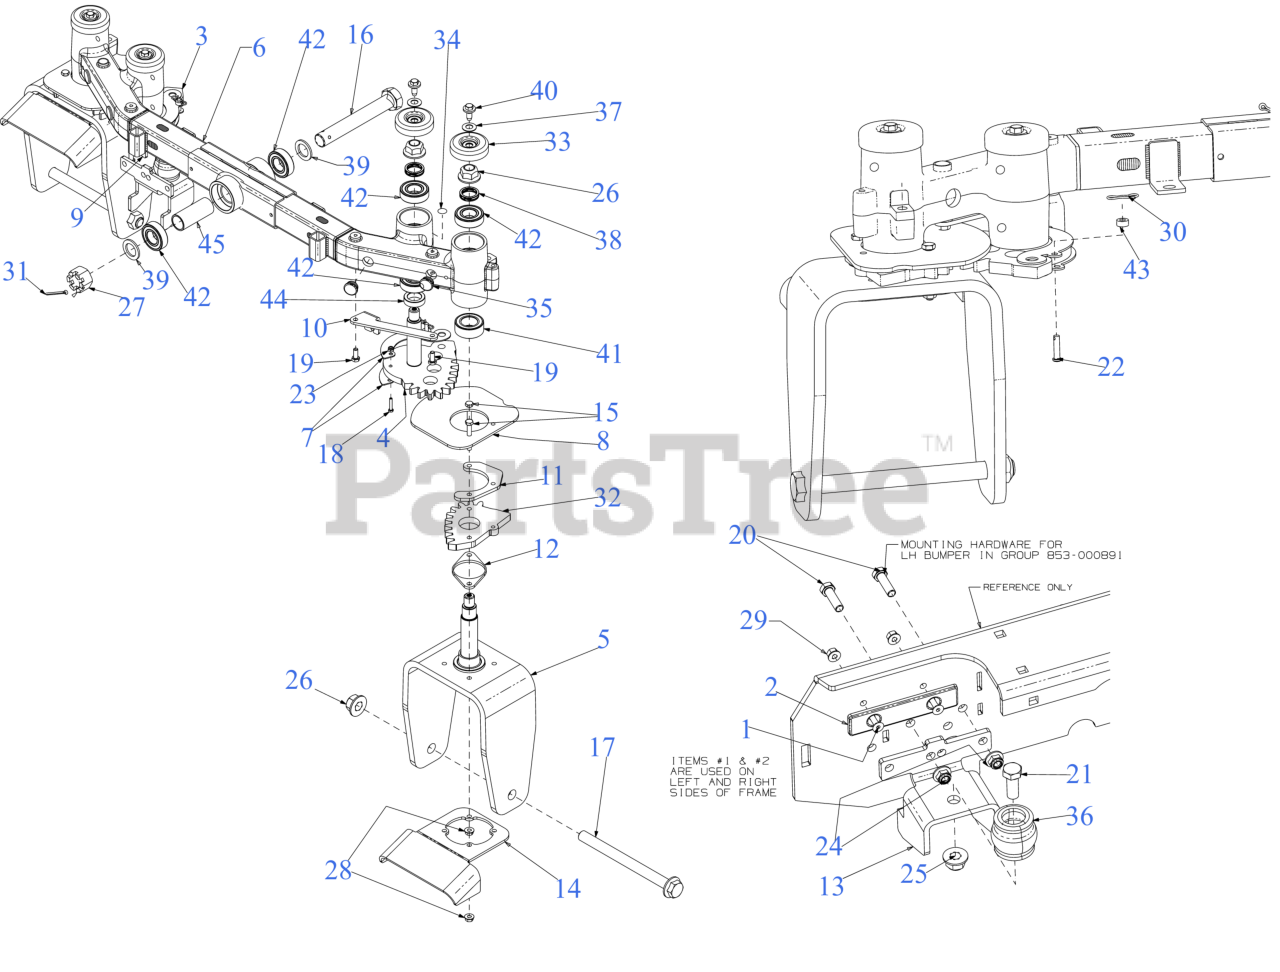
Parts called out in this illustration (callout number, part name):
1	SCREW-FLAT HEAD CA
2	PLATE-LIFT WEAR
3	LEFT HAND STEERING GEAR ASSEMBLY
4	RIGHT HAND STEERING GEAR ASSEMBLY
5	YOKE ASSEMBLY
6	AXLE ASSEMBLY
7	CABLE BEAR MOUNTING BRACKET
12	LOWER GEAR SPACER PLATE
13	BUMPER MOUNTING BRACKET
15	HEX SCREW 5/16-18 x 2.25 GR5
16	HEX HEAD SCREW (1-14 x 7 GR5)
17	SCREW 3/4-16 x 9.00 GR5
18	SCREW #10-24 x 1.00 GR5.1
19	SCREW 5/16-18 x .750
20	SCREW 3/8-16 x 1.25 GR5
21	SCREW 1/2-13 x 1.25 GR5
22	CLEVIS PIN .25 x 1.00
26	FLANGE LOCK NUT 3/4-16 TOP LOCK
27	CASTLE NUT 1.0-14 GR5
28	HEX FLANGE NUT
29	LOCK NUT 1/4
30	BOW TIE COTTER PIN 1/4-5/16
31	SPLIT COTTER PIN 5/32 X 2.00
32	STEERING GEAR YOKE
33	AXLE CAP 2.5"
34	RATCHET CLIP
36	AXIAL BUMPER
37	BELL WASHER
38	WAVE WASHER
39	FLAT WASHER 1.005 x 1.570 x 0.125
41	BALL BEARING 30x52x20
42	BALL BEARING (1.0 x 52 x 15)
45	SPACER 1.00 x 1.25 x 2.99
